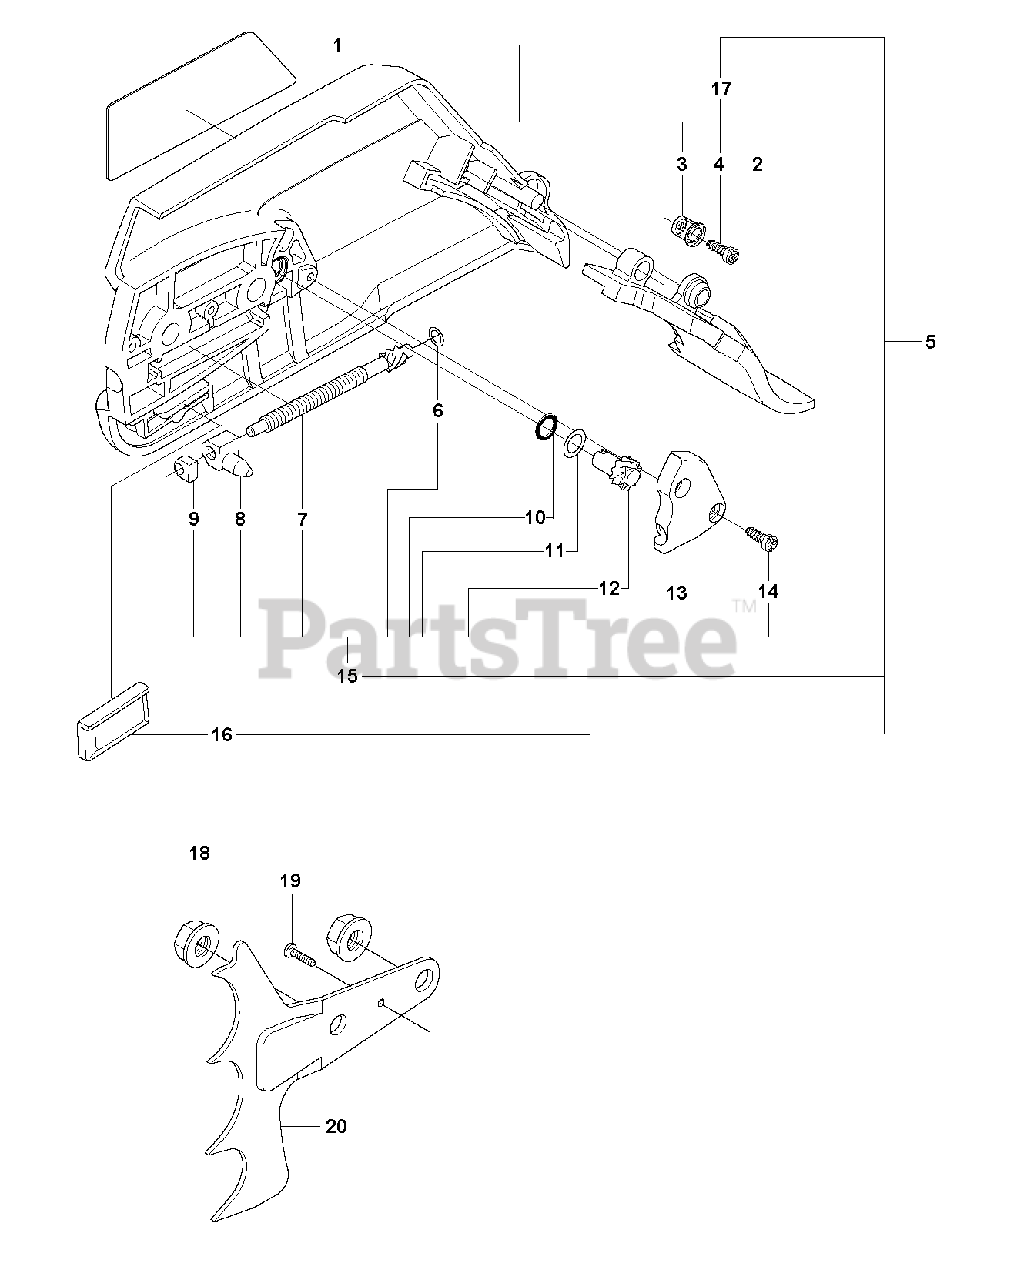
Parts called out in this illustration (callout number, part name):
1	DECAL
2	PROTECTOR
3	WASHER
4	SCREW
5	CHAIN BRAKE COVER
6	WASHER
7	ADJUSTER
8	PAWL
9	SLEEVE
10	O-RING
11	WASHER
12	RP ADJUSTER
13	COVER
14	SCREW
15	KIT-CHAIN TENSIONER
16	CHAIN GUIDE
17	CHAIN BRAKE COVER
18	NUT M8 FLANGE
20	SPIKE OUTER
